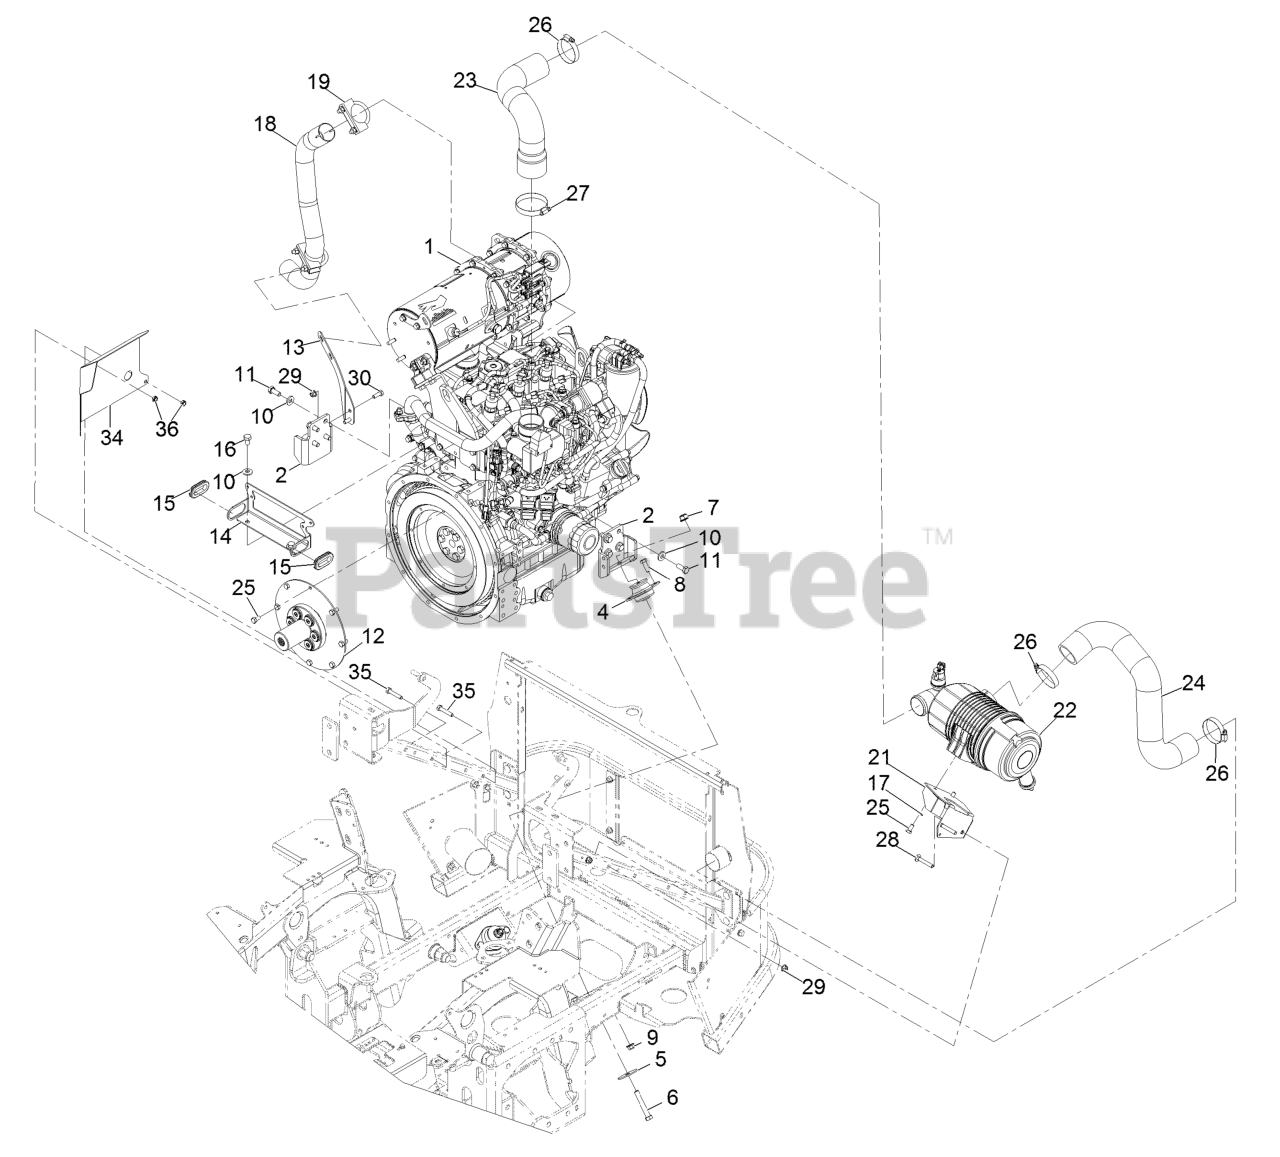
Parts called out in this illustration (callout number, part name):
1	Engine-Yanmar, 3Tnv88C-Dtr5
2	Mount-Motor, Upper
5	Washer-Snubbing
6	Screw-HH
7	Nut-HF, NI
8	Screw-HH 3/8-16 X 1
9	Nut-Nyloc 3/8-16 Flg
10	Washer-Spring Disc 3/8
11	Screw-HH M10-1.5 X 35Mm
12	Coupling-Flywheel
13	Bracket-Mount
14	Bracket-Guide
15	Grommet-Rubber
16	Screw-HH
17	Washer-Belleville
18	Tube-Exhaust
21	Bracket-Cleaner, Air
22	Air Cleaner ASM
23	Hose-Air
24	Hose-Air
25	Bolt
26	Clamp-Hose
27	Clamp-Hose
28	Bolt-Carriage 3/16-18 X 2
29	Nut-Nyloc 5/16-18 Flg
30	Screw-HH 5/16-18 X 7/8
34	Deflector-Air
35	Screw-HH
36	Nut-Nyloc 5/16-18 Thin
